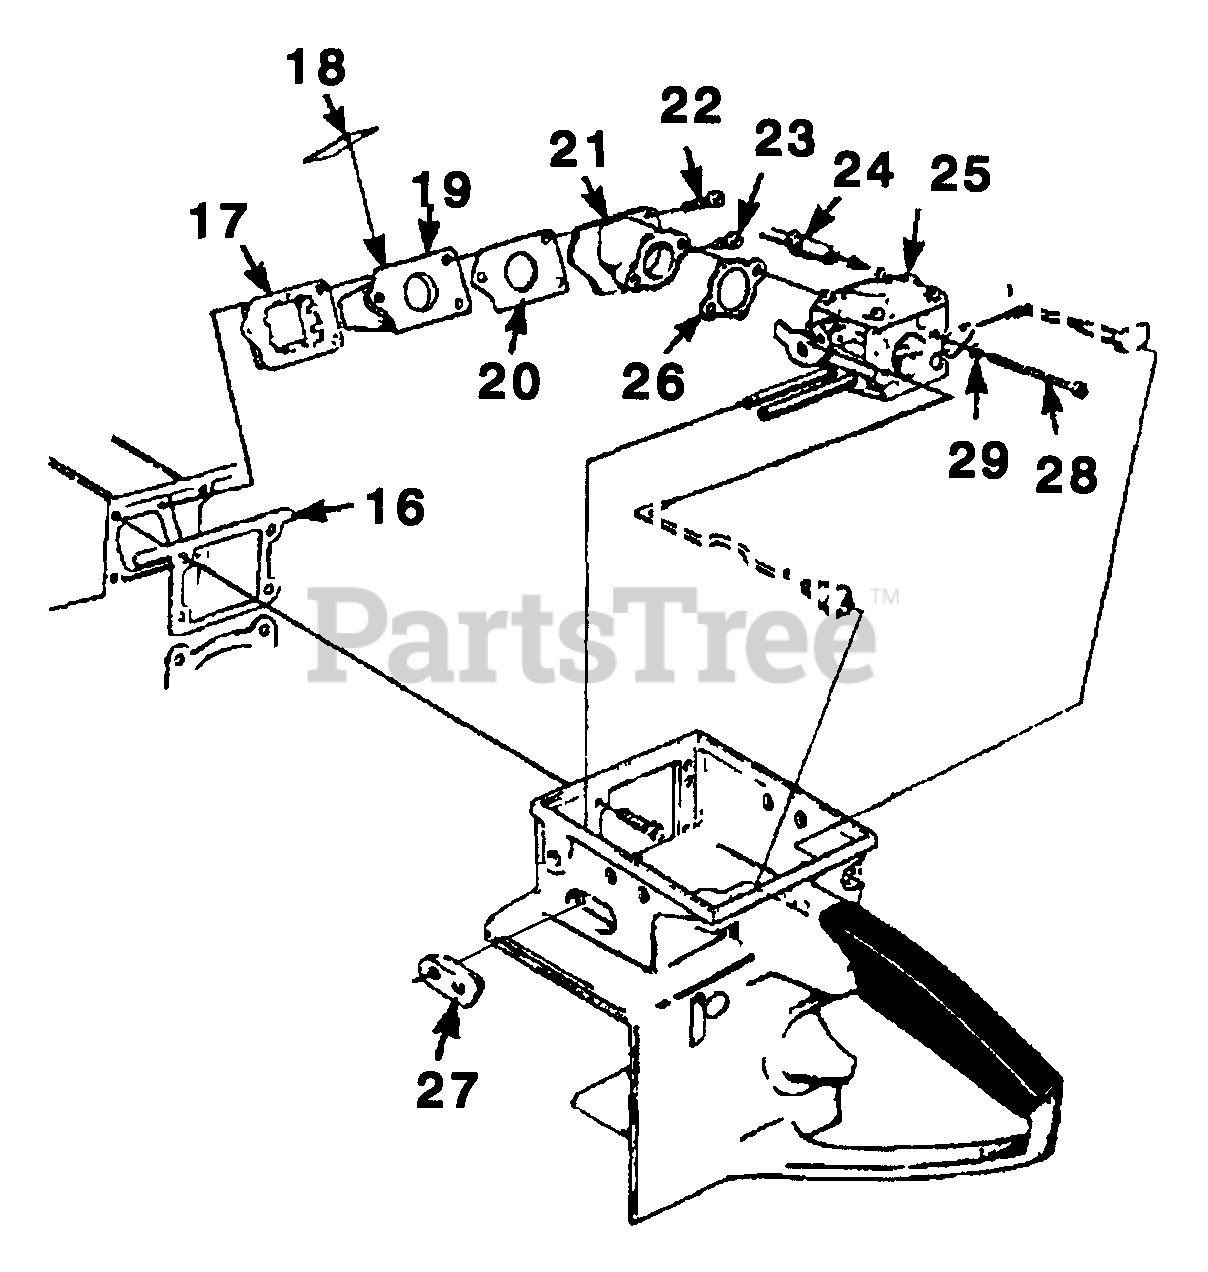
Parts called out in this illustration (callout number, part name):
17	RETAINER - Reed
18	REED - Valve
19	SEAT - Reed Valve
21	SPACER - Carburetor
22	SCREW - (8-32 X 1 1/4")
23	SCREW - Thread form (8-32 X 1 1/4")
24	FUEL LINE
25	CARBURETOR
27	GROMMET
28	SCREW - (10-32 X 1 7/8")
29	WASHER - Lock
